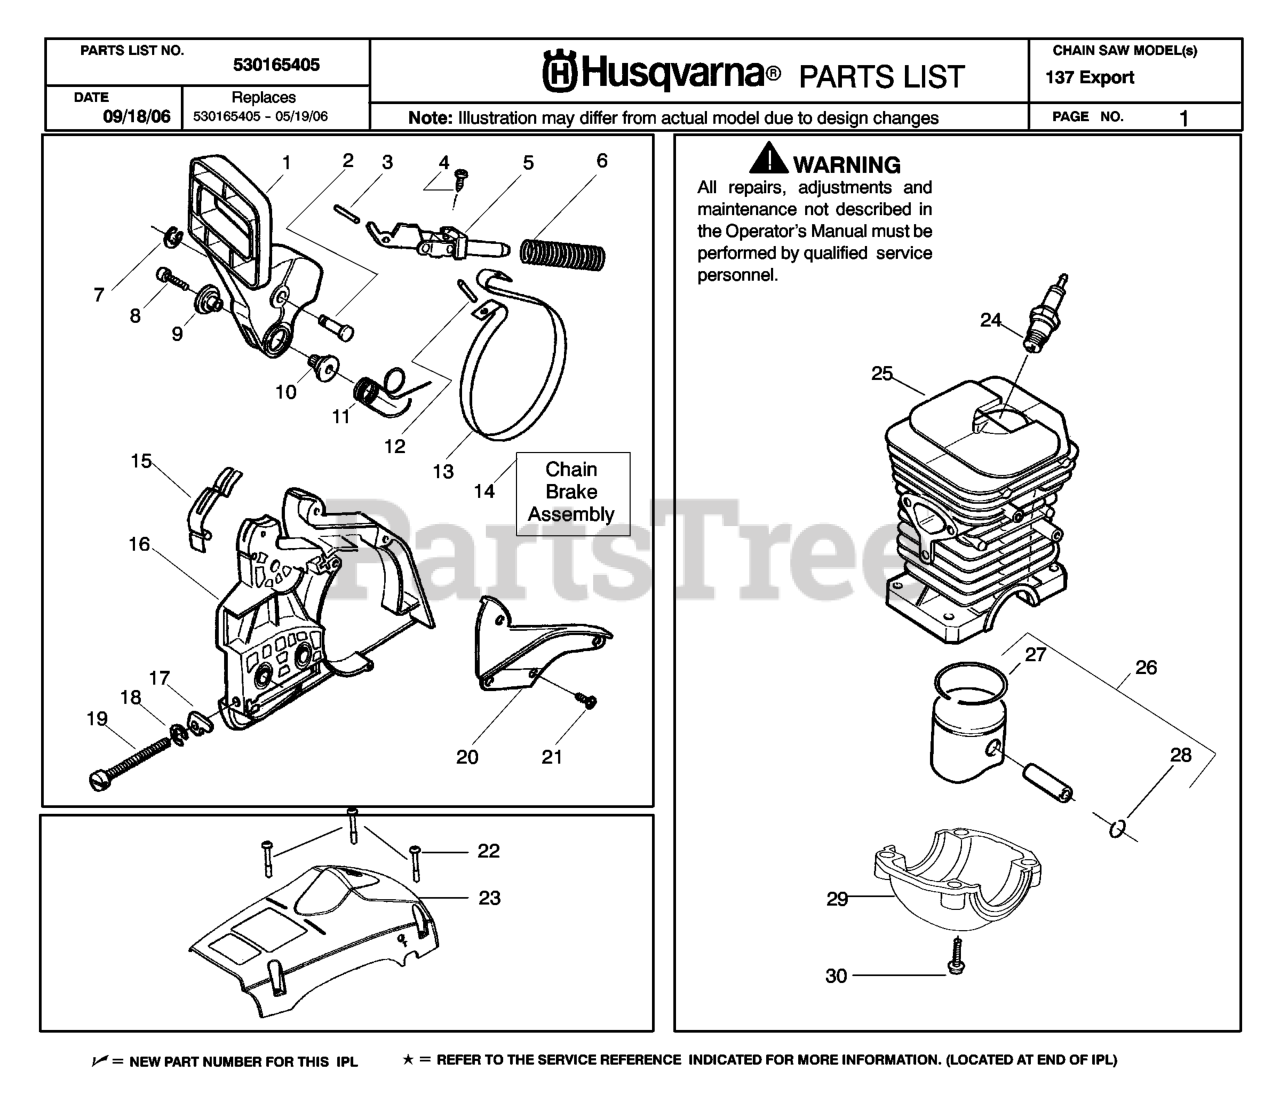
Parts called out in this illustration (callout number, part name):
1	%TUBE ASSY COMPLETE
4	BUSHING
5	CLAMPING SLEEVE
7	BOLT FLANGE
10	SHAFT LOWER
13	RP WARNING DECAL
14	DECAL WARNING "NO BLADES"
15	BOLT FLANGE
